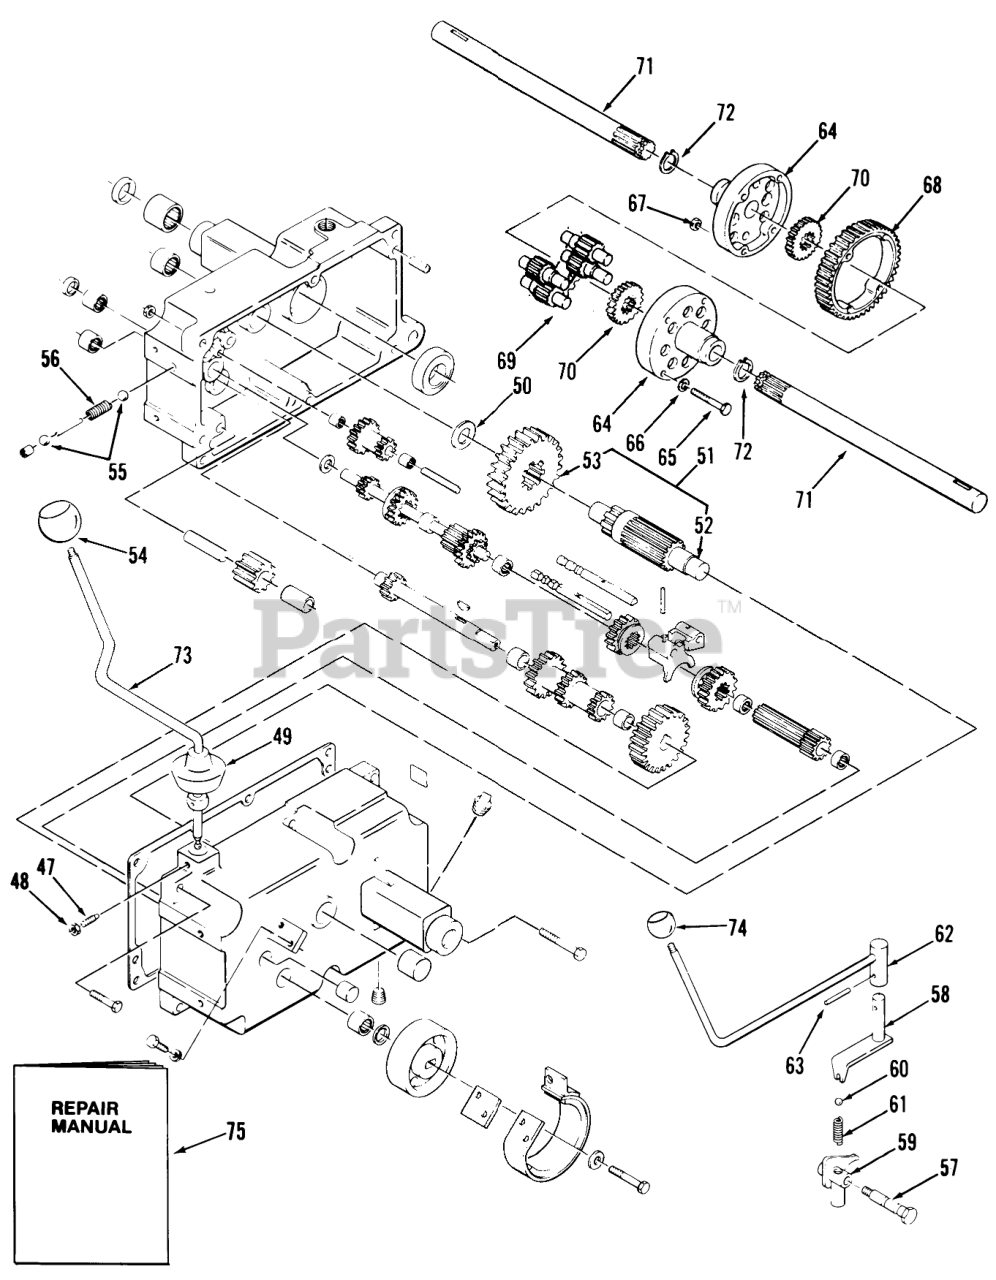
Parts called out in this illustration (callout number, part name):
47	SETSCREW
48	Nut
49	COVER-DUST
50	WASHER-THRUST
51	GEAR ASM
52	PINION SHAFT
55	BALL-DETENT
56	SPRING-SHIFT STOP
57	BOLT-DETENT
58	SHIFT ASM
59	Shift Fork
60	BALL-DETENT
61	SPRING-SHIFT STOP
62	Shift Lever HI-Low Range
63	PIN-SPIROL
64	CASE-DIFFERENTIAL
65	Bolt 3/8-16 x 3 1/4
66	WASHER
68	DIFFERENTIAL BULL GR
69	GEAR-PINION, 11T
70	AXLE GEAR
71	AXLE-REAR
72	Snap Ring
73	Gear Shift Lever
74	Knob
75	MANUAL
